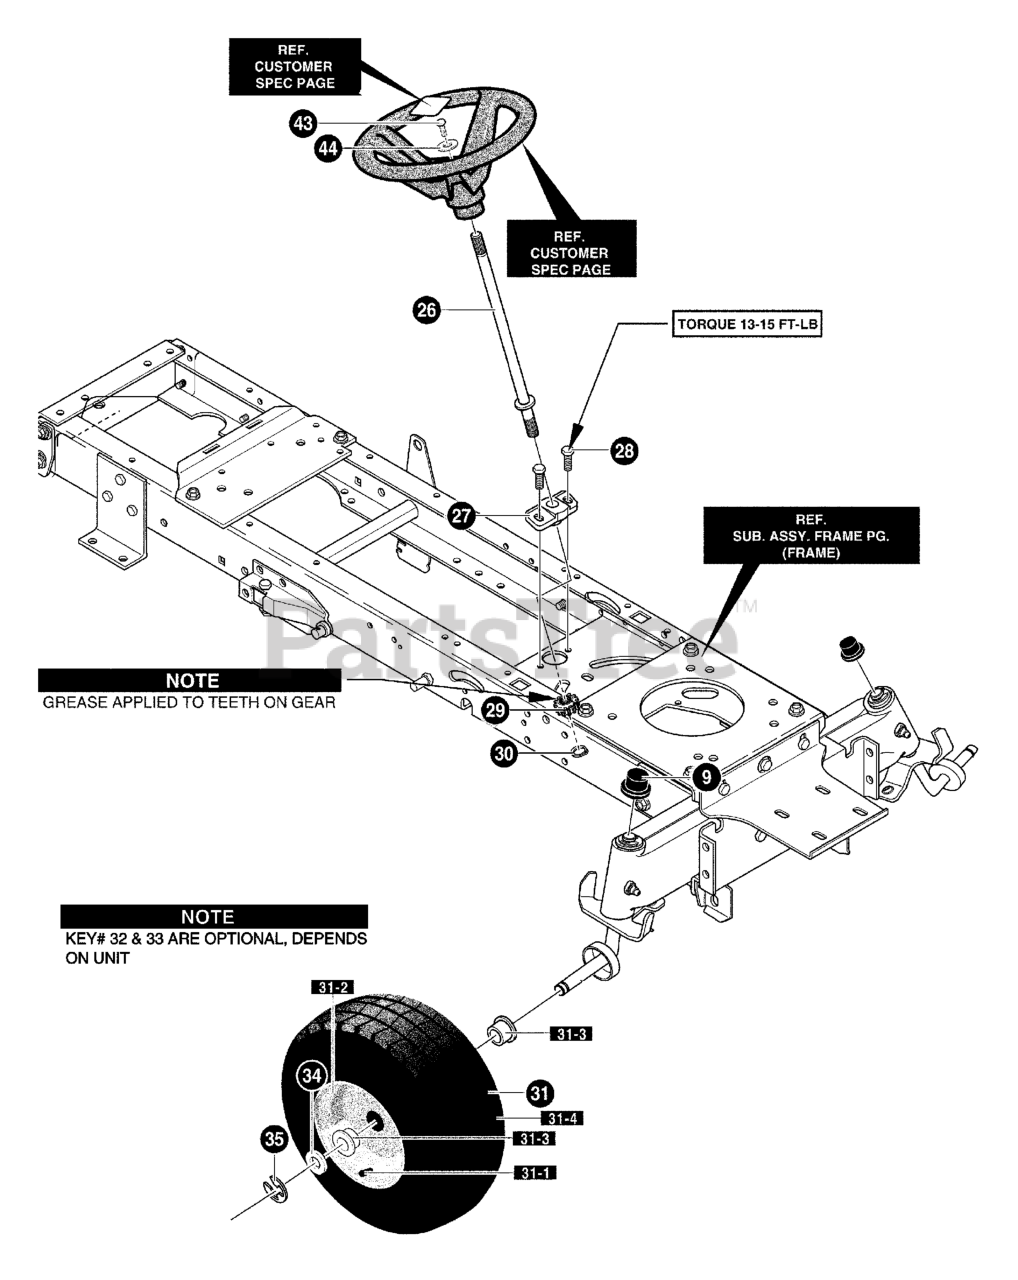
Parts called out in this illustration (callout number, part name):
9	DUST HUB CAP
26	SHAFT, STEERING BOLT ON
27	BEARING-LOWER
28	SCREW, 5/16-18 x .75 HHWATAP
29	GEAR PINNION
30	RING, RET E.
31	TIRE & RIM 15X6.00-6
31-1	VALVE STEM
31-3	BEARING
31-4	TIRE 15X6.00-6
34	WASHER, FLAT .765 x 1.81 x .059
35	E-RING .574IDX.050/.750SH
43	SCREW, 1/4-20X.75
44	FLATWASHER .281X1.25X.06
